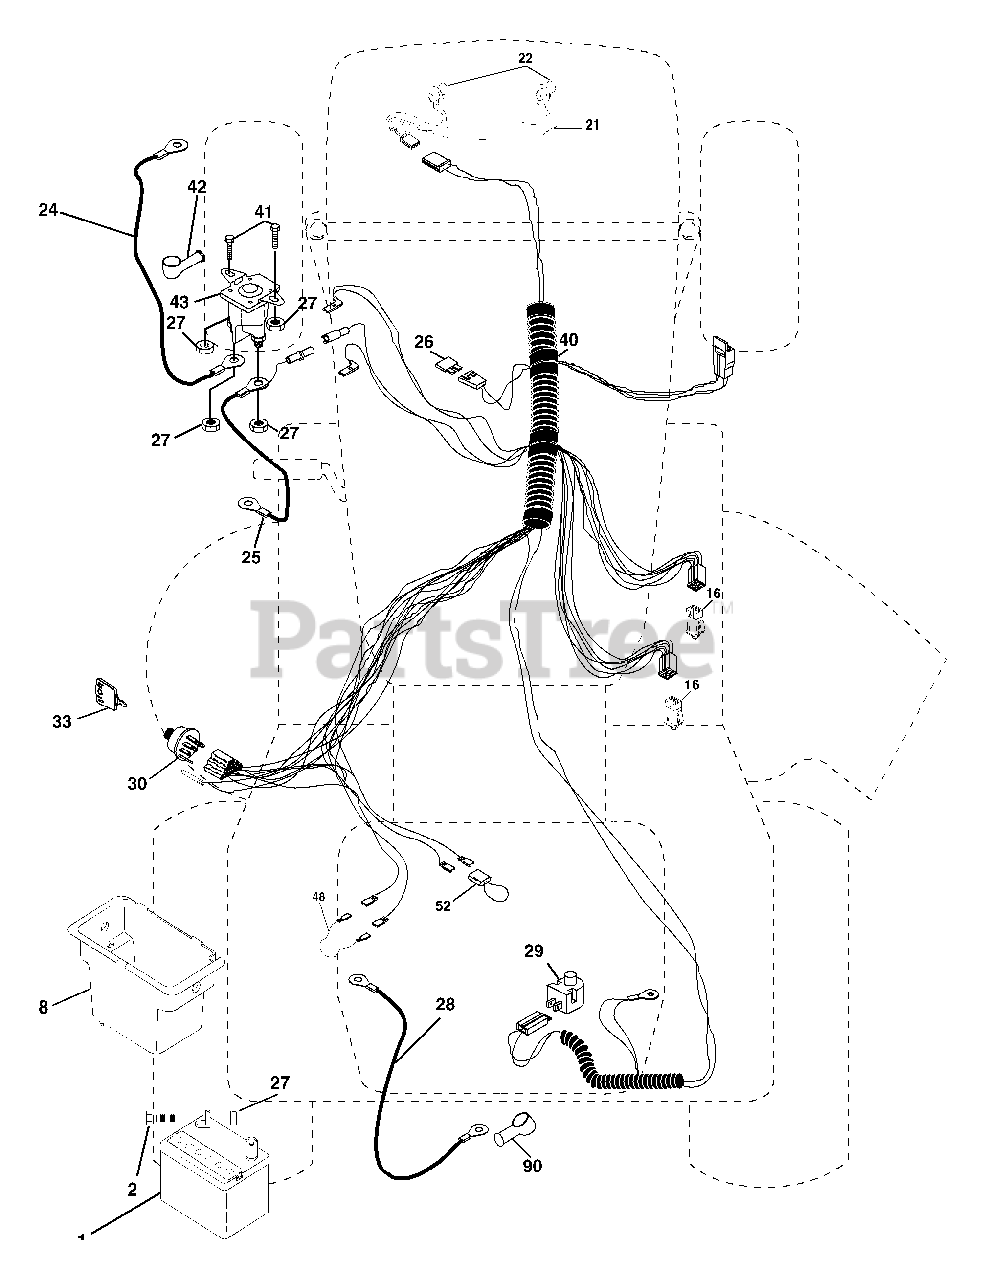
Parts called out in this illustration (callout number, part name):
1	Battery
2	Bolt Hex Hd 1/4-20unc X 3/4
8	Box Battery
16	Switch Interlock
21	Harness Asm Light W/4152j
22	Bulb Light #1156
24	Cable Battery 6 Ga 11" red
25	Cable Battery
26	Fuse 20 AMP
27	Nut Keps Hex 1/4-20 Unc
28	Cable Ground 6 Ga 12" black
29	Switch Plunger Nc Gray
30	Switch Ign
33	Key Ign
40	Harness Ign
41	Bolt Blk Fin Hex 1/4-20
42	Cover Terminal Red
43	Solenoid
48	Adapter Ammeter
52	Protection Wire Loop
90	Cover Terminal Battery
